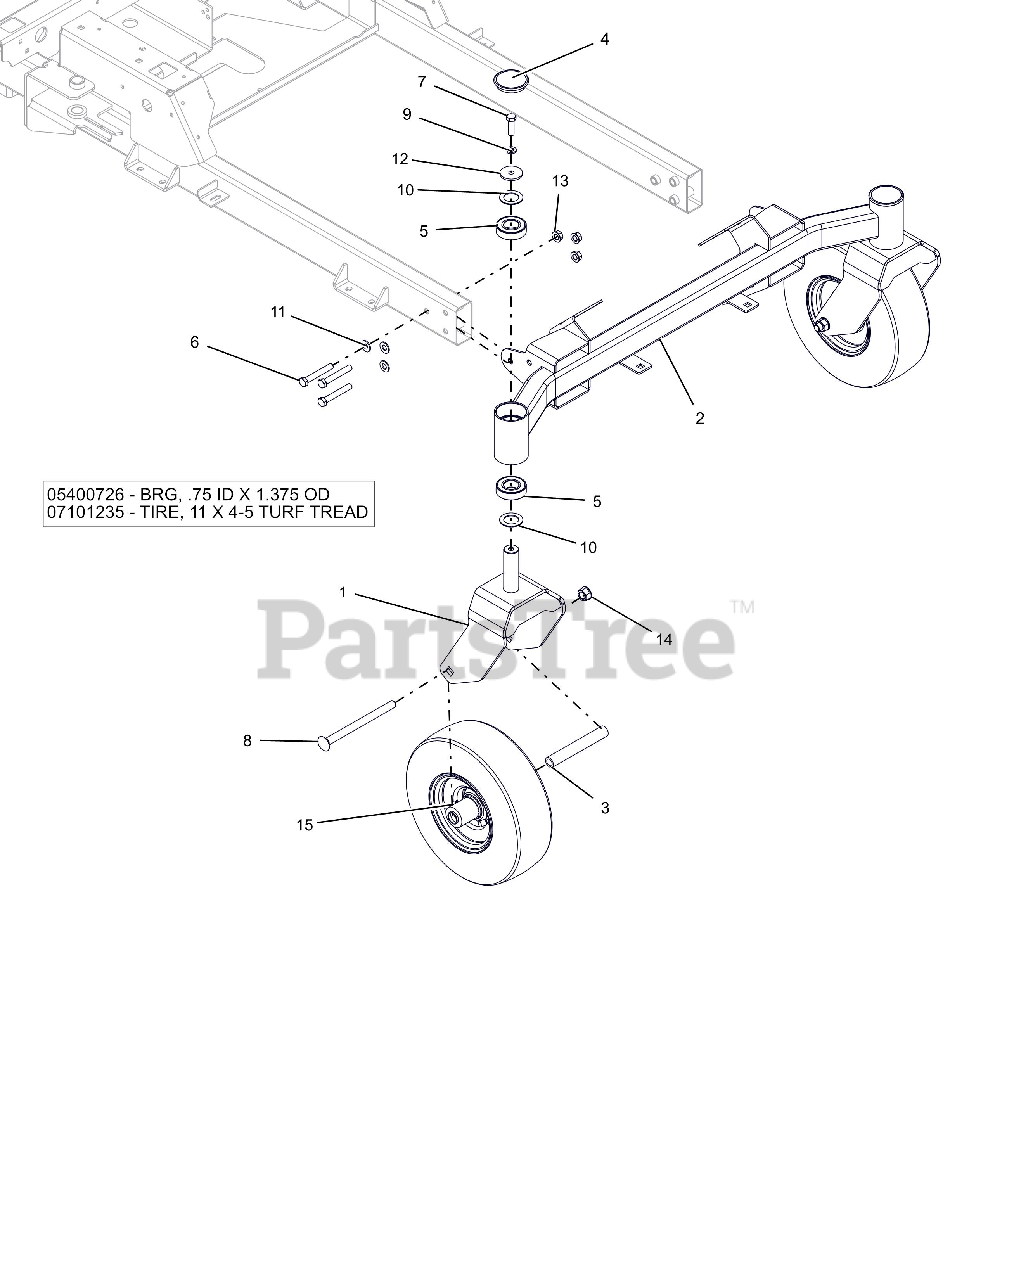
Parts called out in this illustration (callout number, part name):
1	WMT, CASTER FORK
2	WLDMT, AXLE FRONT
3	SPACER, ROLLED WHEEL
4	CAP, DUST
5	BRG,BALL 1.00X2.00X.563(1641)
6	BLT-HEX .38-16X2.50 GR8 YWZC
7	@BLT-HEX .38-16X1.25 GR5 YWZC
8	BLT-RDHDSQNK .50-13X6.50 GR5 Y
9	@WSHR-LK .38X.094 REG YWZC
10	WSHR-HRD-THRS 1.007X1.542X.062
11	WSHR-HDND .406X.812X.055
12	WSHR-FL-STL .380X1.50X.125YWZC
13	NUT-LK-TOP-FLG .38-16 GRG YWZC
14	@NUT-LK-TOP-FLG .50-13 YWZC
15	ASM, WHL/TIRE 11X4.00-5
15	BRG, .75 ID X 1.375 OD
15	LAWN TIRE FRONT, 11/4-5 TURF TREAD
